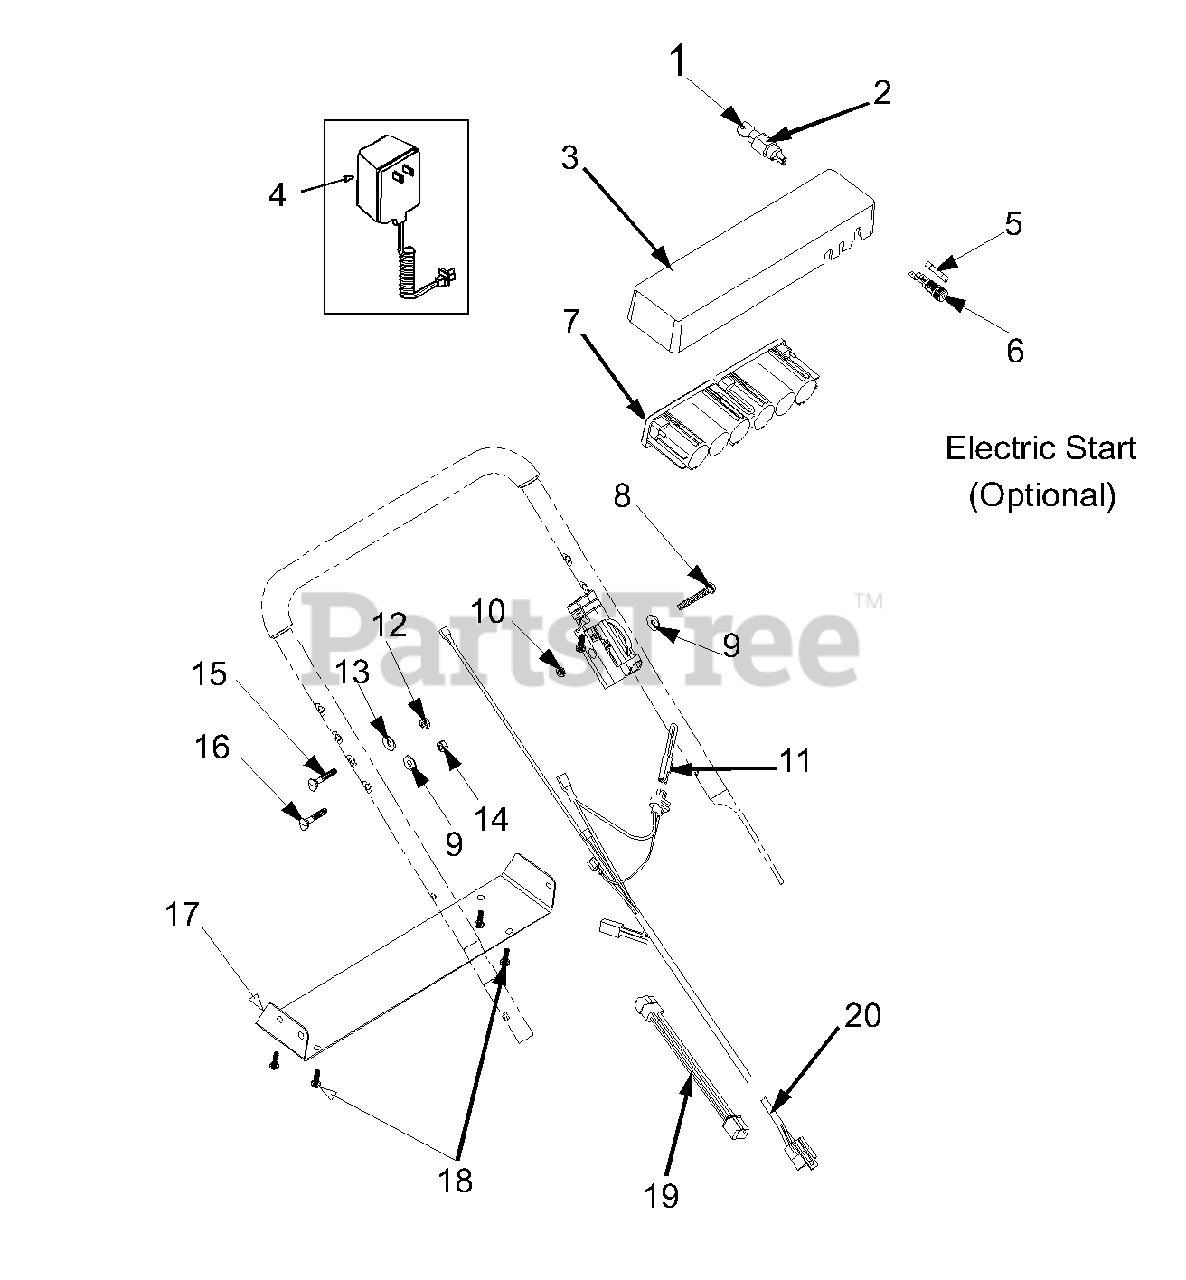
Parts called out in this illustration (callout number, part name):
1	Ignition Key
2	Key Switch
3	Battery Tray
4	Battery Charger
5	Fuse 7.5 Amp
6	Fuse Holder
7	Battery 12V
8	Hex Screw:1/4-20:2.0
9	Bell Washer .265 x .75 x .062
10	Special Hex Nut 5/16-18
11	Plug
12	Nut 5/16-18
13	Bell Wash .340 ID x .872 OD
14	Hex Nut 1/4-20
15	Carriage Bolt 5/16-18 x 1
16	Carriage Screw
19	Harness Extension
20	Harness
